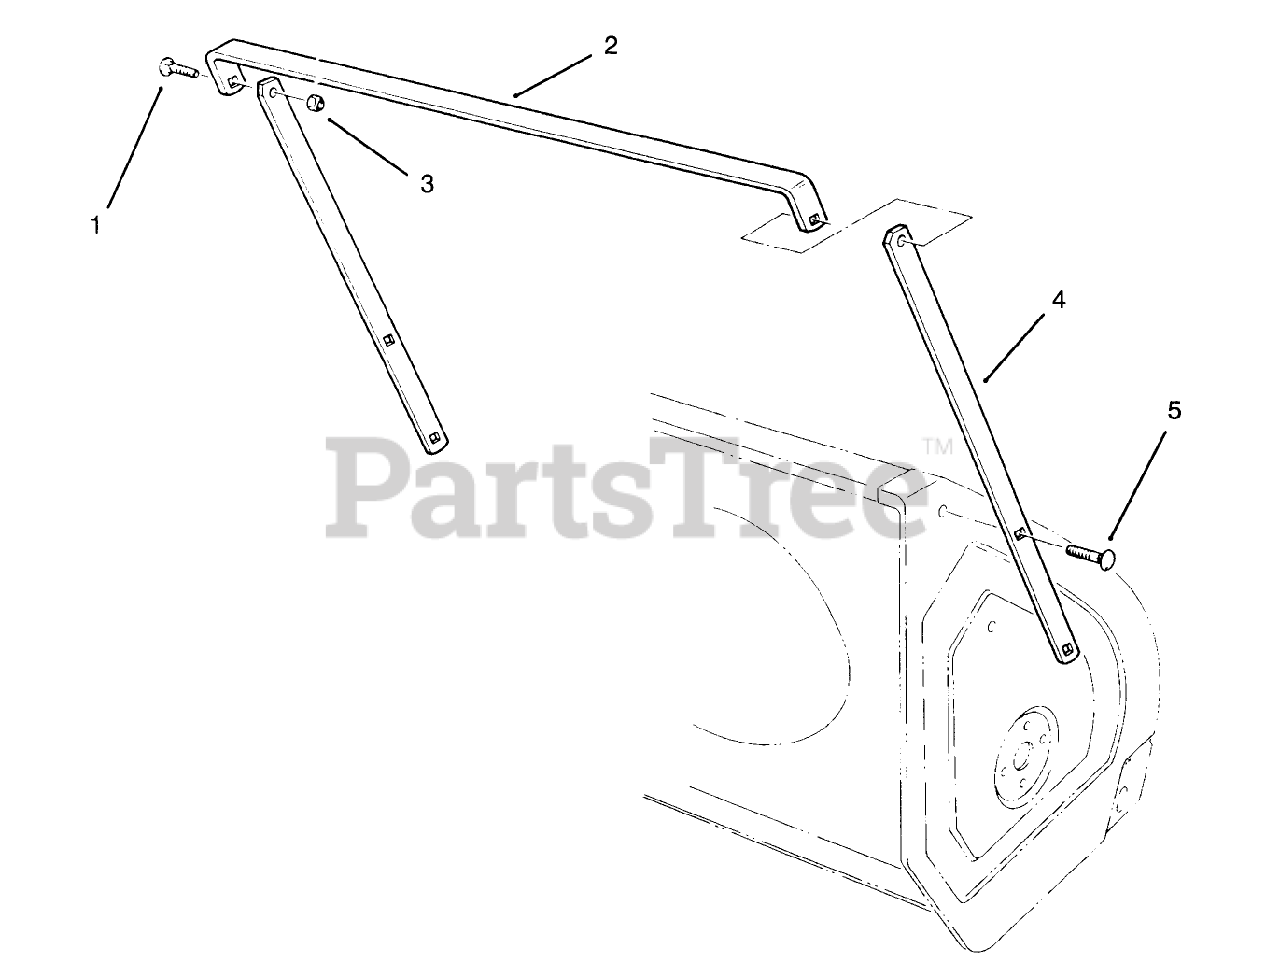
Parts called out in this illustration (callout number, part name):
1	SCREW-CARR
3	NUT-LOCK, NI
4	Breaker-Side
5	BOLT-CARR
